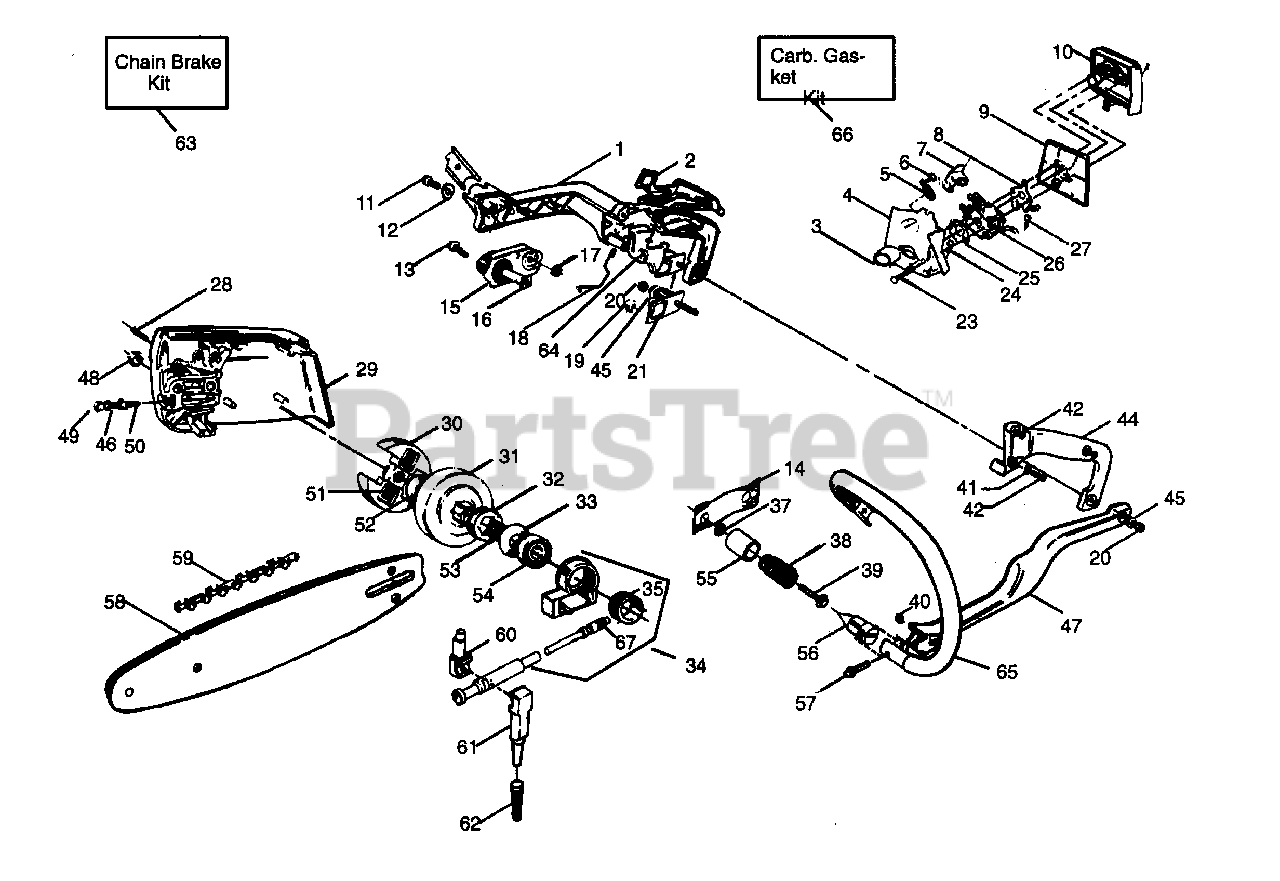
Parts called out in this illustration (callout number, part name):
1	Rear Handle
2	Throttle Lockout
3	Grommet
5	Air Flow Plate
6	Screw
9	Air Filter
10	Air Filter Cover
13	Screw
15	Top Isolator
17	Nut
18	Throttle Wire
21	Rear Isolator
26	Carburetor-WT-109
29	Bar Clamp
30	Clutch Ass'y.
31	Clutch Drum
32	Rim Sprocket
34	Oiler Ass'y. (Inc. 35, 67 and Oiler Body)
35	Worm Gear
38	Isolator Spring
40	Nut
42	Screw
44	Rear Handle
47	Handle Brace
49	Screw
50	Adj. Pin
51	Clutch Spring
56	Isolator Plug
60	Oil Outlet
61	Oil Inlet Line
62	Oil Filter
63	Chain Brake Kit
64	Throttle Trigger
65	Handlebar
66	Carb. Gasket Kit
67	Gear
